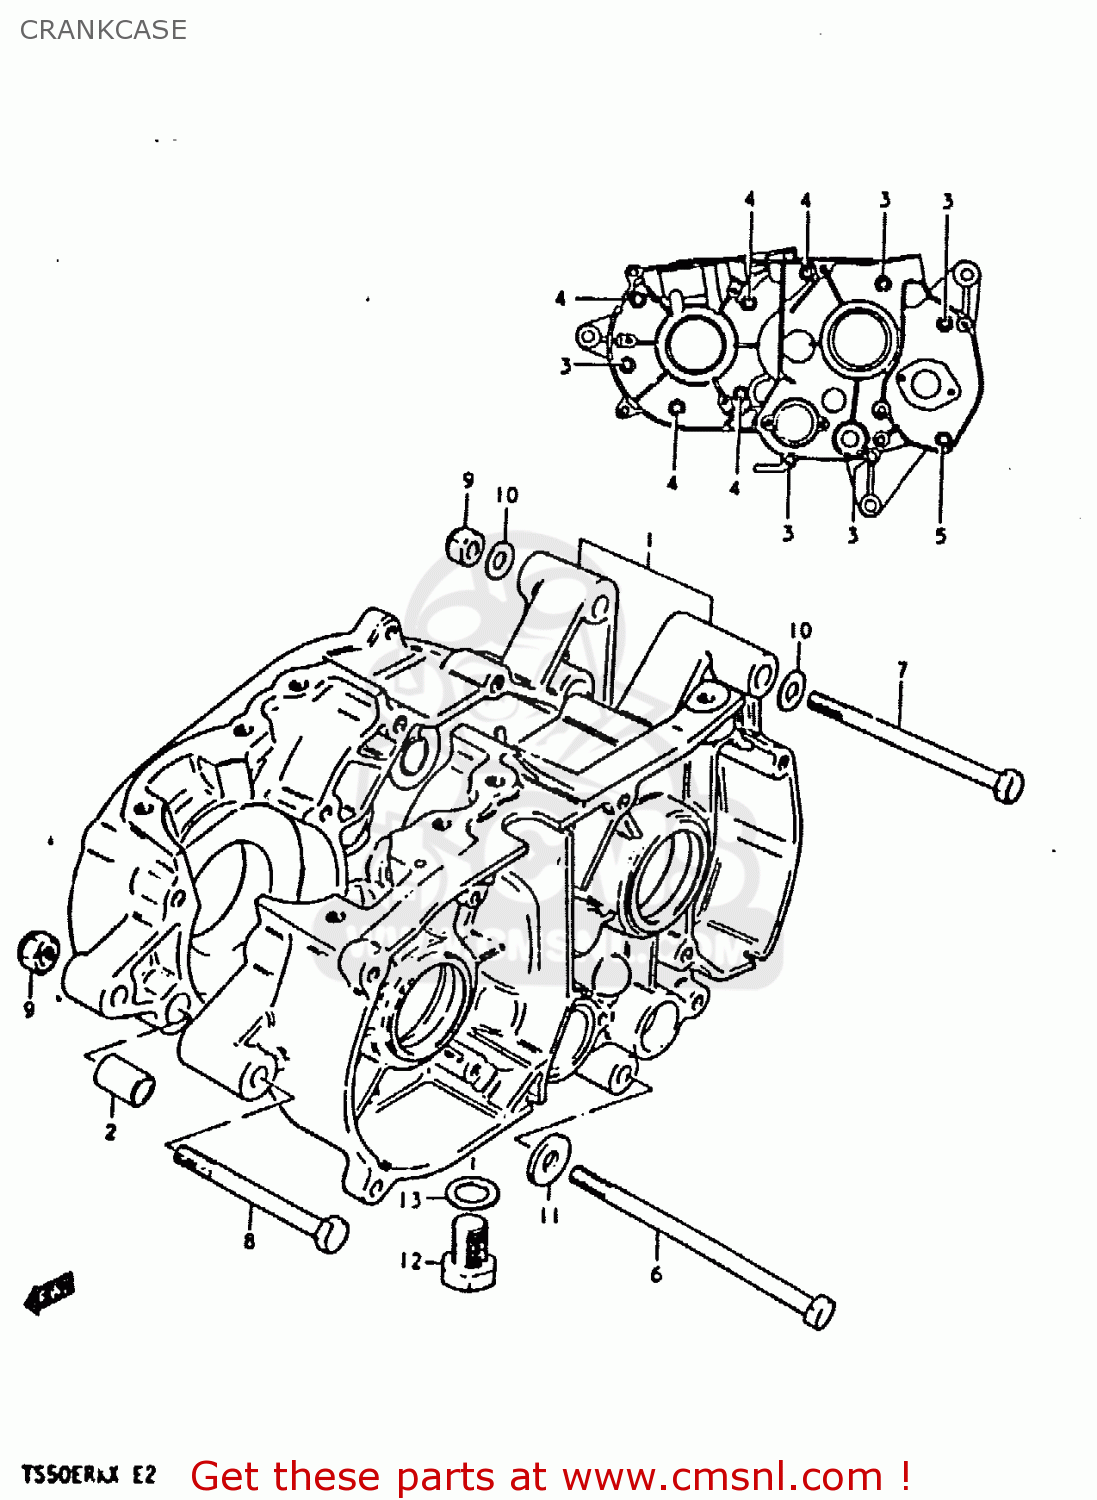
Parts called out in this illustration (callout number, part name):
1	CRANKCASE SET
2	PIN
3	SCREW (6X45)
4	SCREW (6X35)
5	SCREW
6	BOLT
7	BOLT
8	BOLT 8X75
9	NUT
10	WASHER
11	WASHER
12	BOLT 10X20
13	GASKET(10X14X3.6) (NAS)
